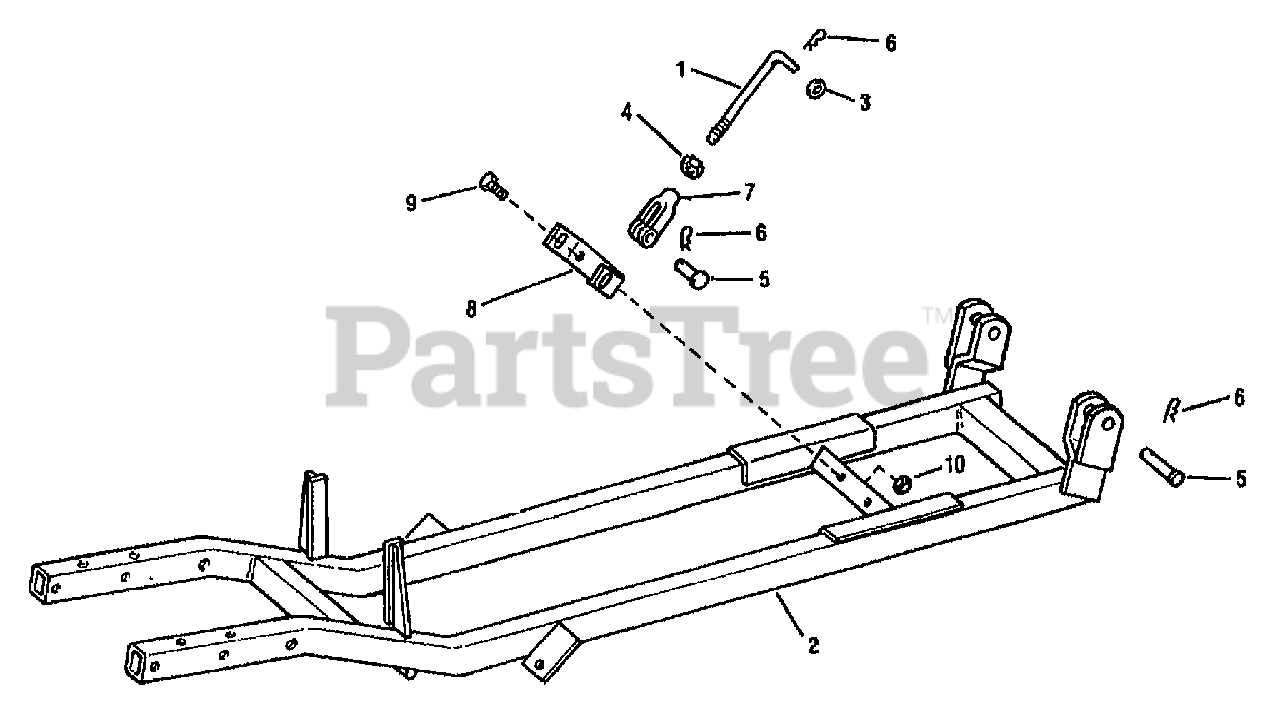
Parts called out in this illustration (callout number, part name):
1	ROD-LIFT
3	WASHER-1.305X.649X.098 ZP
4	NUT-HEX
5	PIN-CLEVIS
6	PIN-HITCH .125X2.56 ZP
7	ROD-END
8	BRACKET-LIFT
9	SCR-HFLK 3/8-16X1.25 ZP
10	NUT-HFLK 3/8-16 ZP
